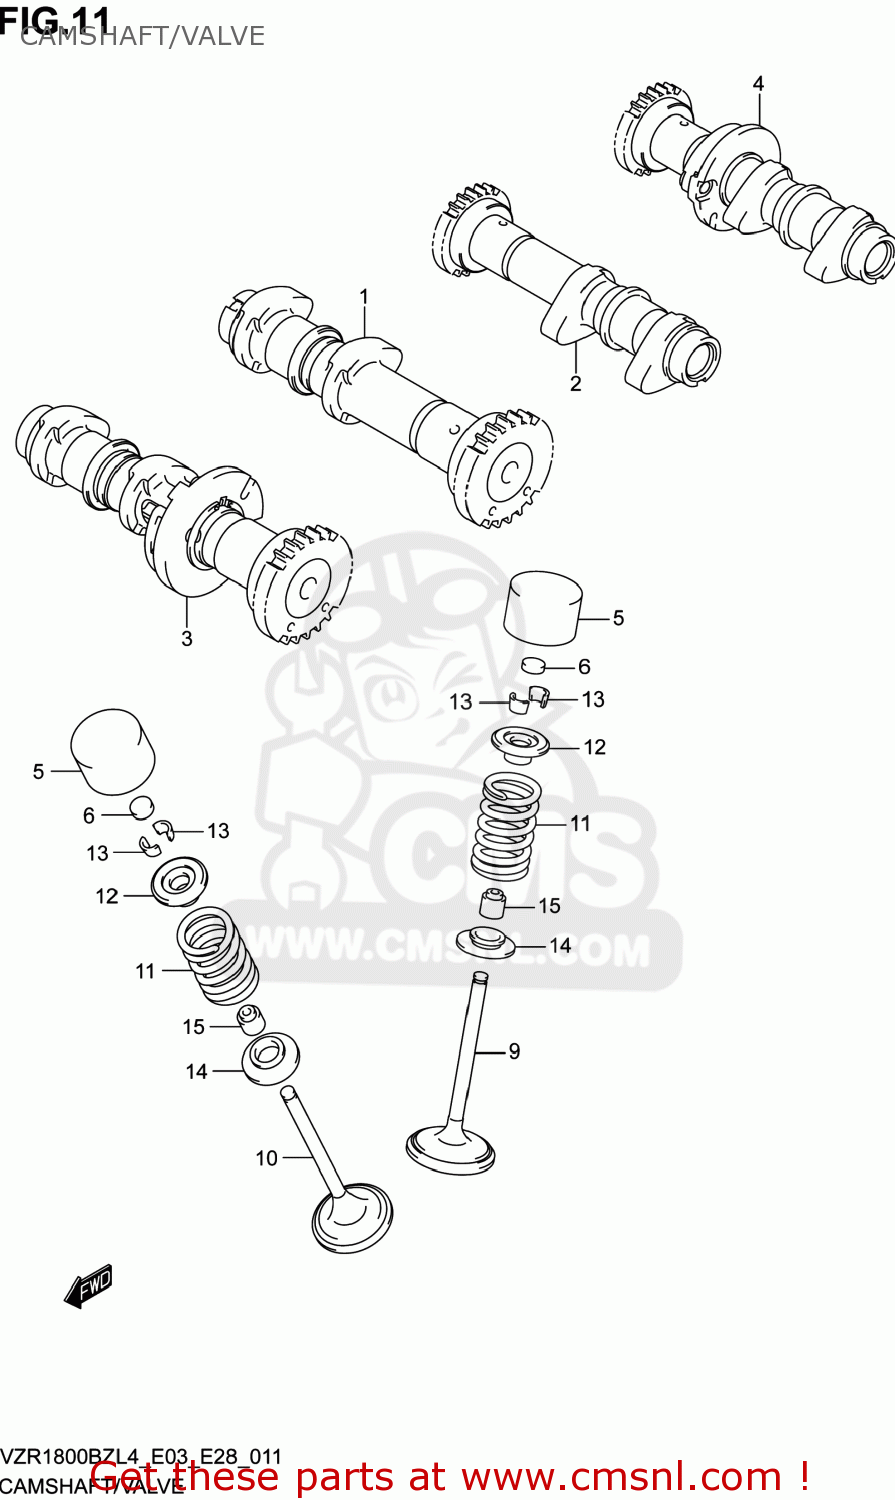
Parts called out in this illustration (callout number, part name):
1	CAMSHAFT,INTAKE FR
2	CAMSHAFT,INTAKE RR
3	CAMSHAFT,EXHAUST FR
4	CAMSHAFT,EXHAUST RR
5	TAPPET
6	SHIM,TAPPET(T:2.3)
7	SHIM SET,TAPPET
8	CASE,TAPPET SHIM
9	VALVE,INTAKE
10	VALVE,EXHAUST
11	SPRING,VALVE
12	RETAINER,VALVE SPRING
13	COTTER,VALVE
14	SEAT,VALVE SPRING
15	SEAL,OIL(6X12.8X10.2)
